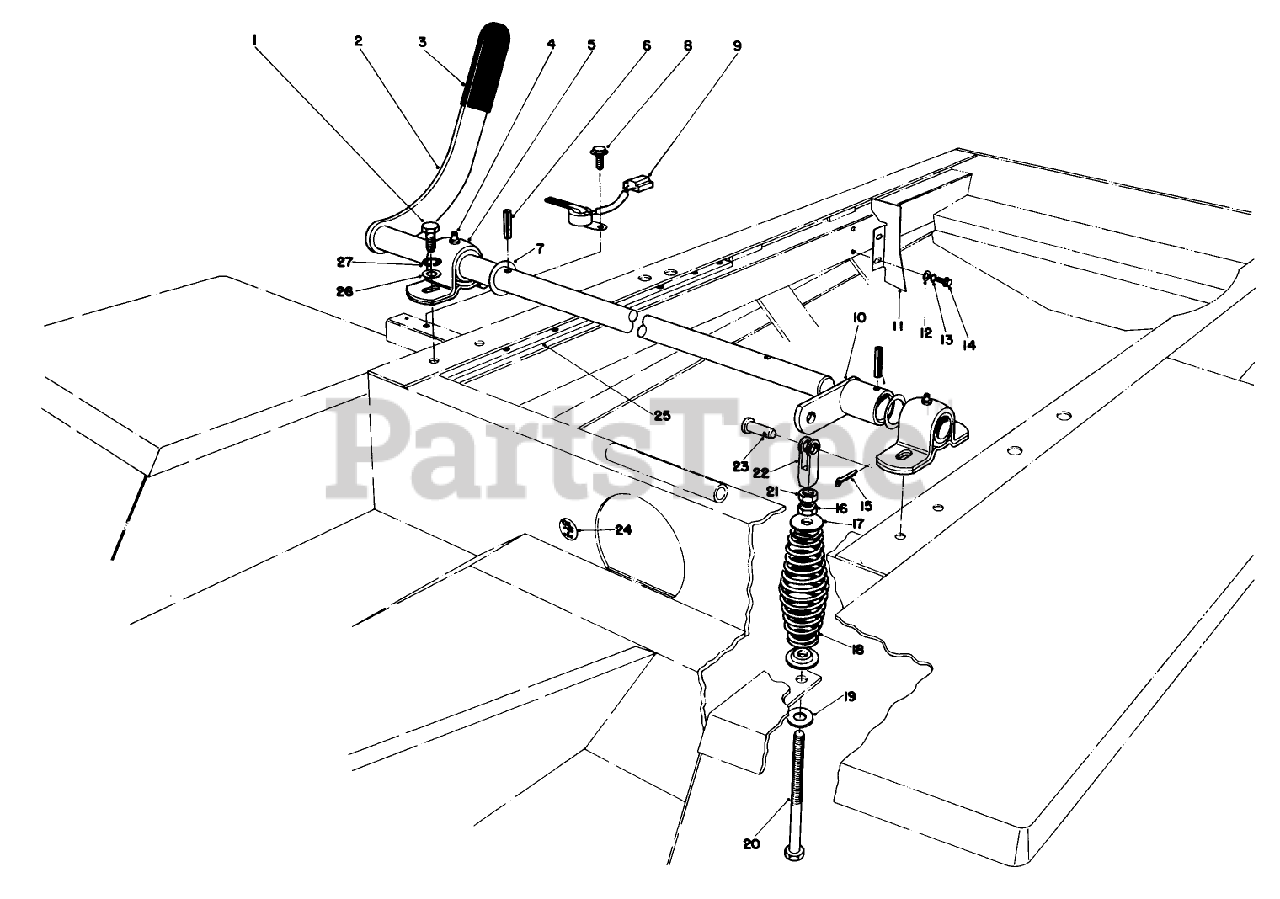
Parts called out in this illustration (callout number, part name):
1	SCREW-HH
3	GRIP-HANDLE
4	FITTING-GREASE
5	BEARING
6	PIN-SPRING
7	THRUST WASHER
8	SCREW-HWHTF
12	WASHER-PLAIN
13	SCREW-HH
14	SCREW-THD ROLL, HWH
15	SCREW-HH
16	NUT-HEX
17	SPRING RET TOP
19	WASHER
20	SCREW-ADJUSTING
21	NUT-HJ
23	PIN-CLEVIS
24	OIL DECAL
26	WASHER-FLAT
27	SCREW-HH
